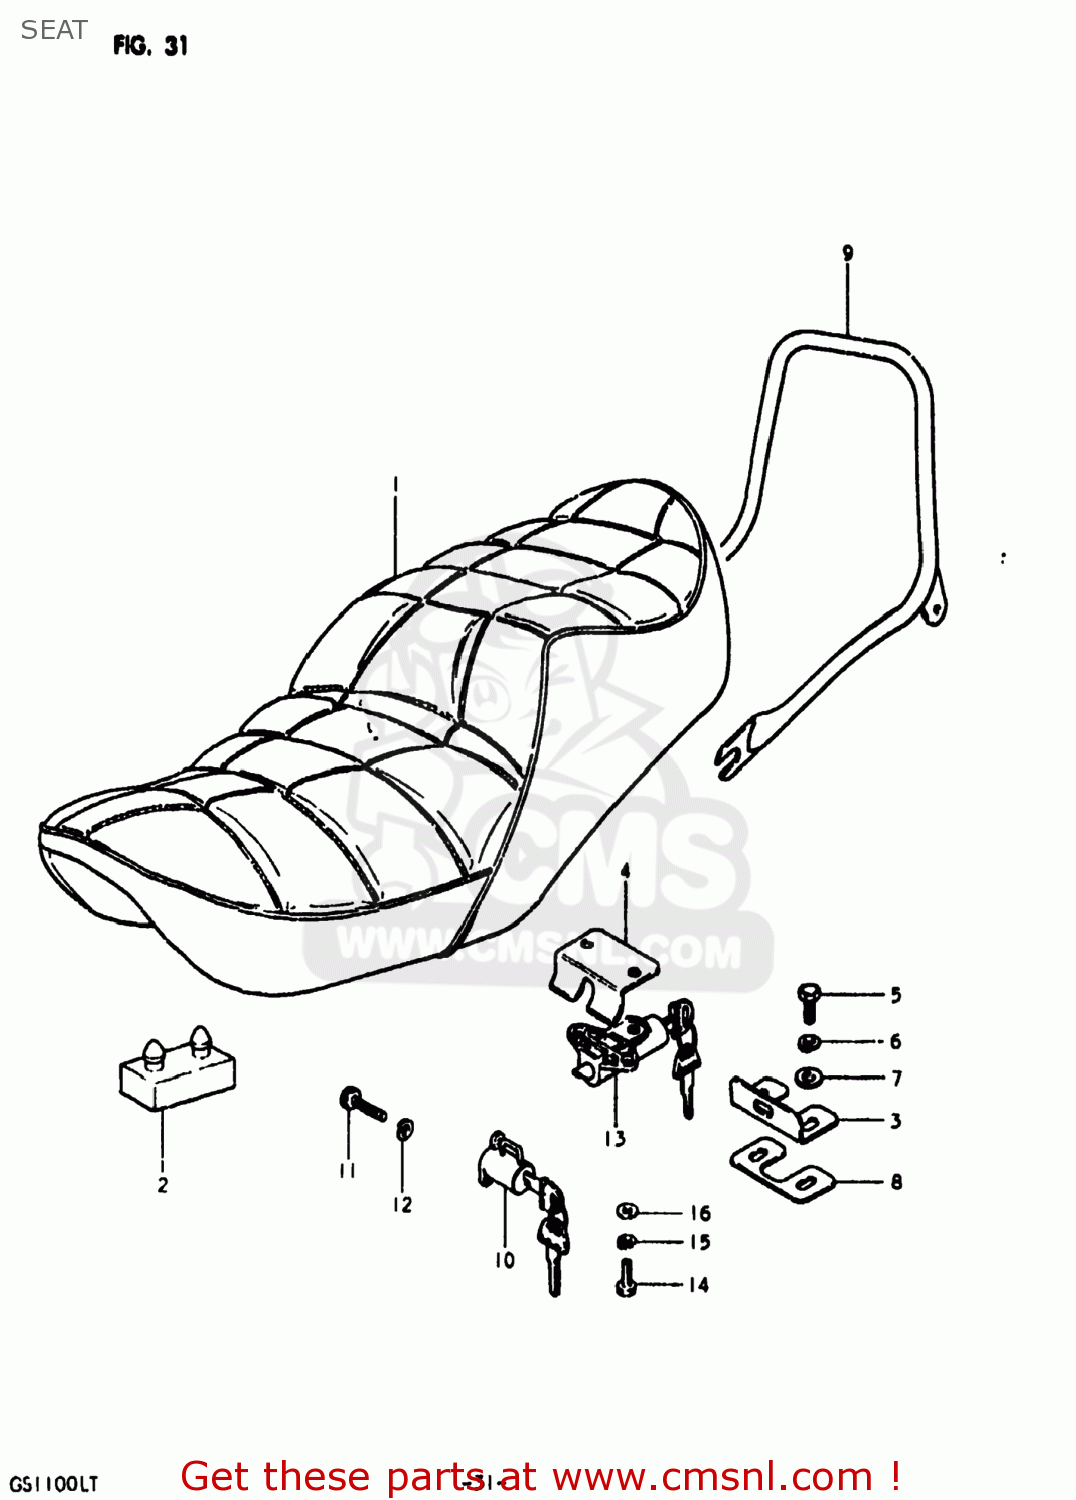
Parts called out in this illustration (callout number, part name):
1	SEAT ASSEMBLY
2	CUSHION
3	STRIKER,SEAT LOCK
4	PLATE,SEAT LOCK
5	BOLT, UPPER
6	LOCK WASHER
7	WASHER 6MM
8	SHIM,SEAT LOCK STRIKER
9	HANDLE,PILLION RIDER
10	LOCK ASSEMBLY,HELMET
11	BOLT
12	LOCK WASHER
13	LOCK ASSEMBLY,SEAT
14	BOLT
15	LOCK WASHER
16	WASHER 6MM
